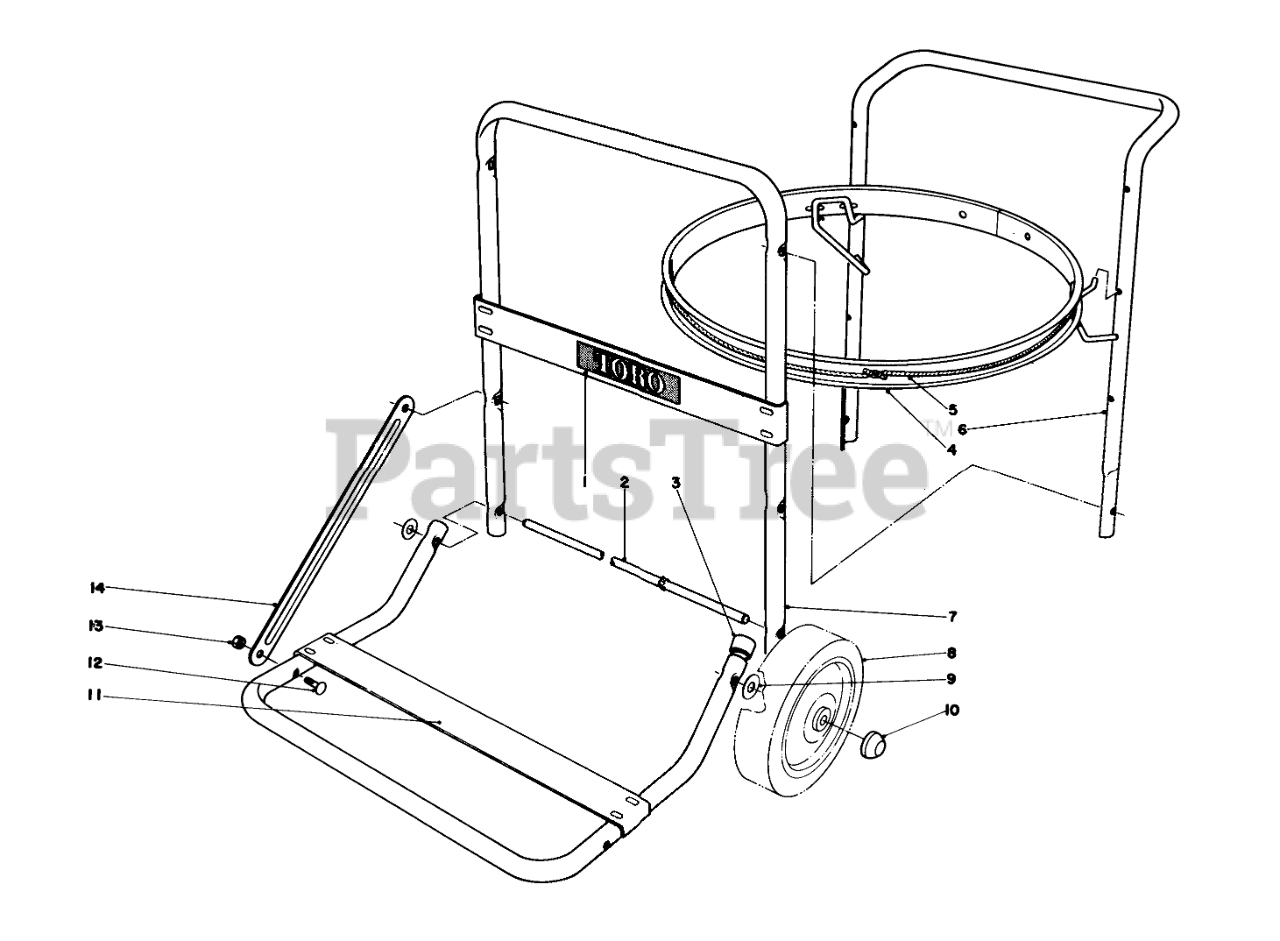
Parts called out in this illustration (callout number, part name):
1	Decal
3	Plastic Plug Button
5	Retainer Cord
6	Upper Handle
7	Lower Handle
8	Wheels
9	WASHER-PLAIN
10	Hub Caps
12	SCREW-CARR
13	NUT-HEX
14	Brace
